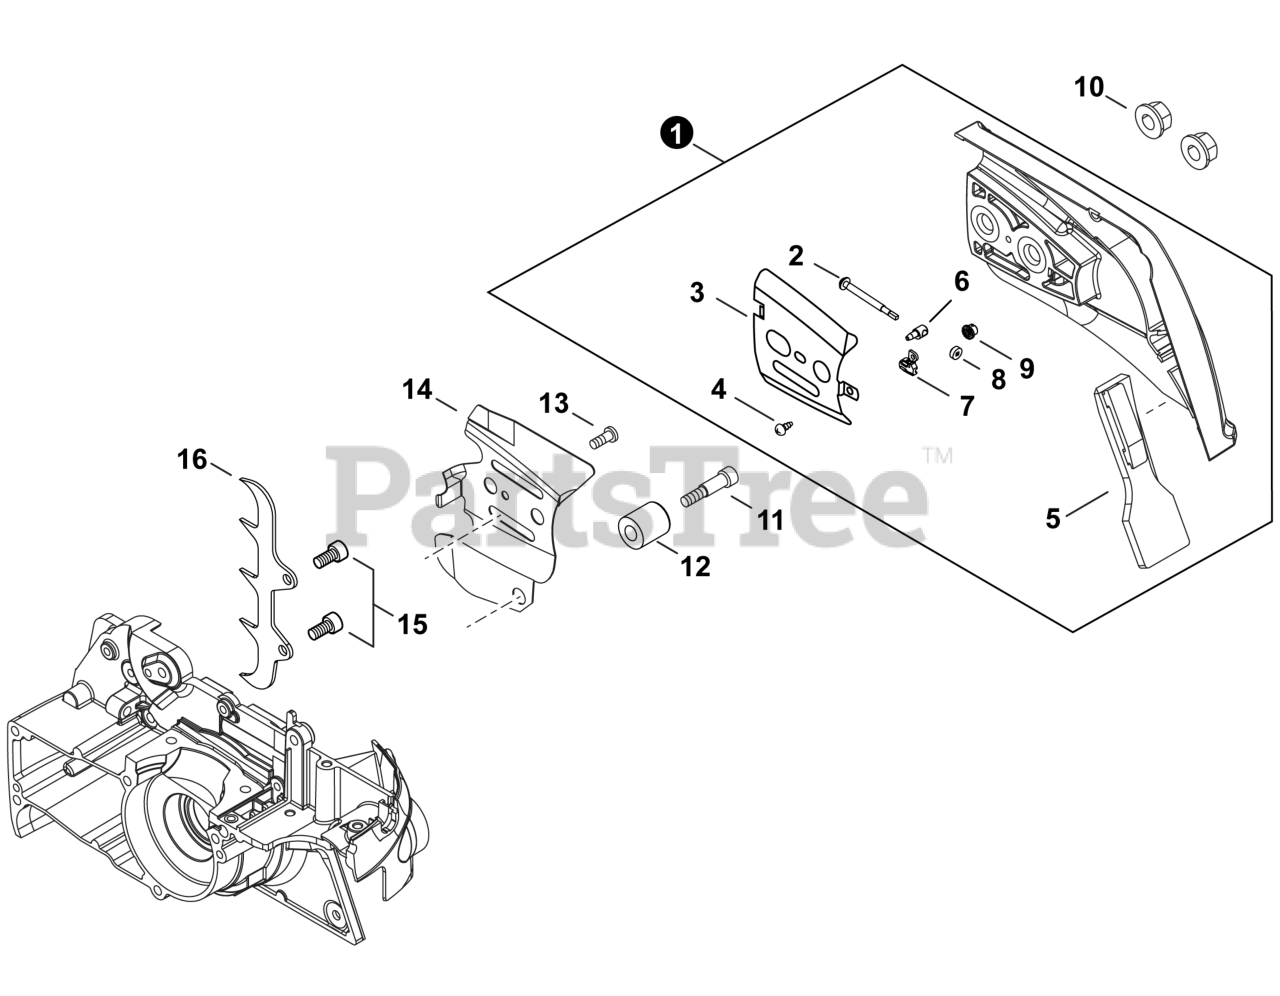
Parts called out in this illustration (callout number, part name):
1	COVER ASSY, CLUTCH
2	SCREW, CHAIN TENSION
3	PLATE, GUIDE - OUTER
4	SCREW 4×8
5	PROTECTOR
6	TENSIONER, CHAIN
7	COLLAR 8
8	GEAR, BEVEL
9	GEAR, BEVEL
10	NUT, FLANGE M8×1.25
11	BOLT 5×30
12	CHAIN CATCHER
13	SCREW M4×7
14	PLATE, GUIDE - INNER
15	BOLT 5×12
16	SPIKE, BUMPER
